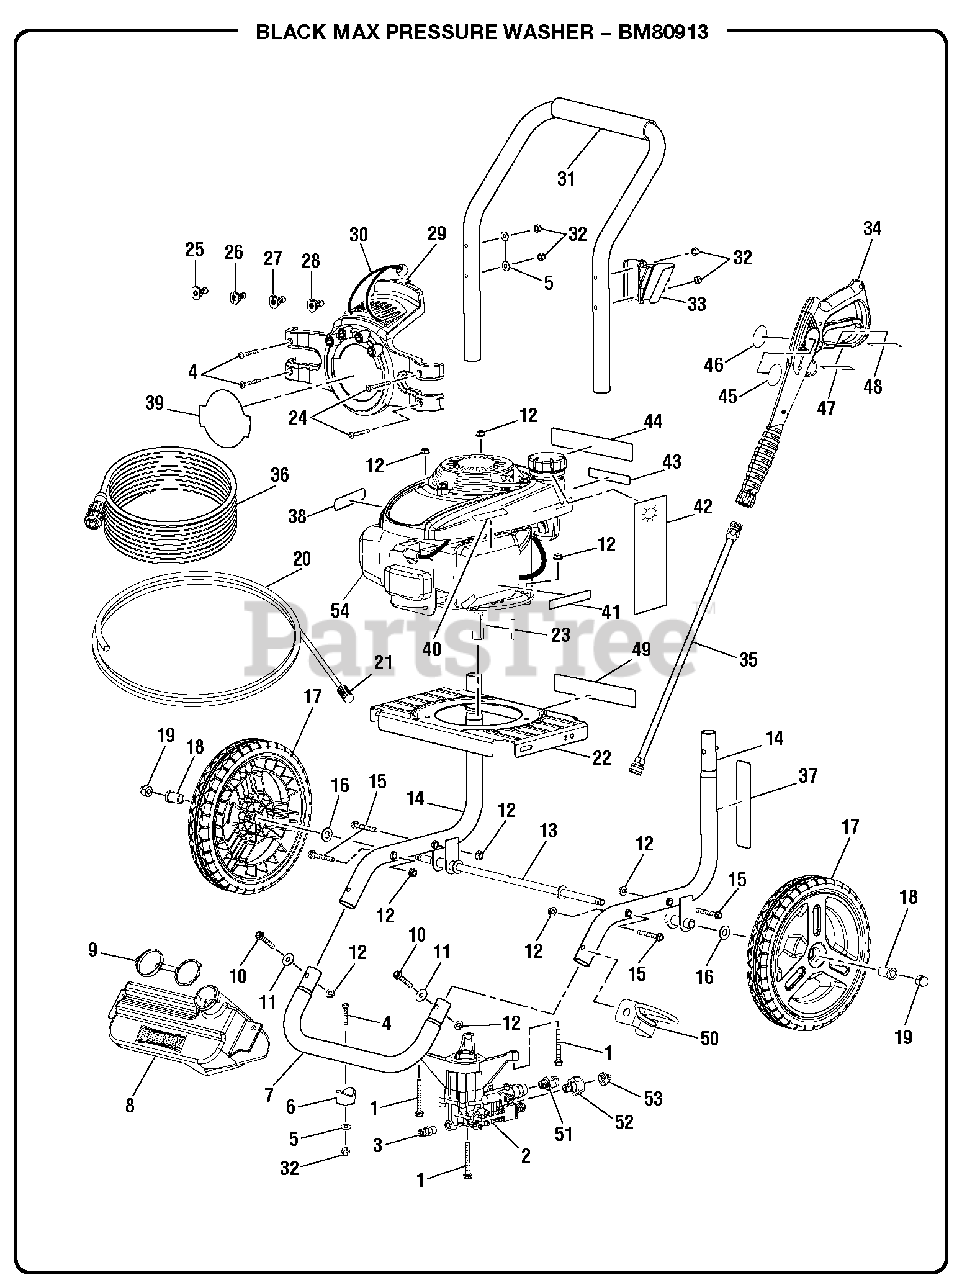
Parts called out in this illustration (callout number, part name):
1	Bolt (M8 x 65 mm, Flange Hd.)
2	Pump
3	Thermal Release Valve
4	Screw (1/4-20 x 1.85 in., T30 Torx Hd.)
5	Washer (1/4 in.)
7	Front Frame
8	Soap Tank
9	Soap Tank Cap
10	Bolt (M8 x 45 mm)
11	Washer (5/16 in.)
12	Hex Nut (M8 x 1-1/4 in.)
14	Main Frame Assembly
15	Bolt w/Washer (M8 x 55 mm, Hex Hd.)
16	Washer (1/2 in.)
17	Wheel
18	Wheel Bushing
19	Acorn Nut
20	Chemical Siphon Tube
21	Chemical Siphon Filter
22	Engine Plate
23	Output Shaft Key (3/16 in. x 40 mm)
24	Screw (1/4-20 x 2.27 in., T30 Torx Hd.)
25	40deg Nozzle
26	Soap Nozzle
27	25deg Nozzle
28	0deg Nozzle
29	Hose and Nozzle Holder Assembly
30	Bungee Cord and Bead Assembly
31	Handle w/Foam
32	Lock Nut (1/4-20)
33	Wand Holder
34	Trigger Handle Assembly
35	Extension Wand
36	Hose (25 ft., 3000 psi)
37	Label (Pump Quick Start)
38	Label (Hot Muffler)
39	Label (Performance)
40	Label (Inquires)
41	Label (Engine Quick Start)
42	Label (Oil Hang Tag)
43	Label (UL Fire Warning)
44	Label (Warning)
45	Label (Wand Warning)
46	Label (Wand Logo)
47	Label (Warning)
48	Label (Wand Rating)
49	Data Label
50	Wand Holder
51	Outlet Tube
52	Inlet Tube
53	Filter Screen (Pump Inlet)
54	Engine
